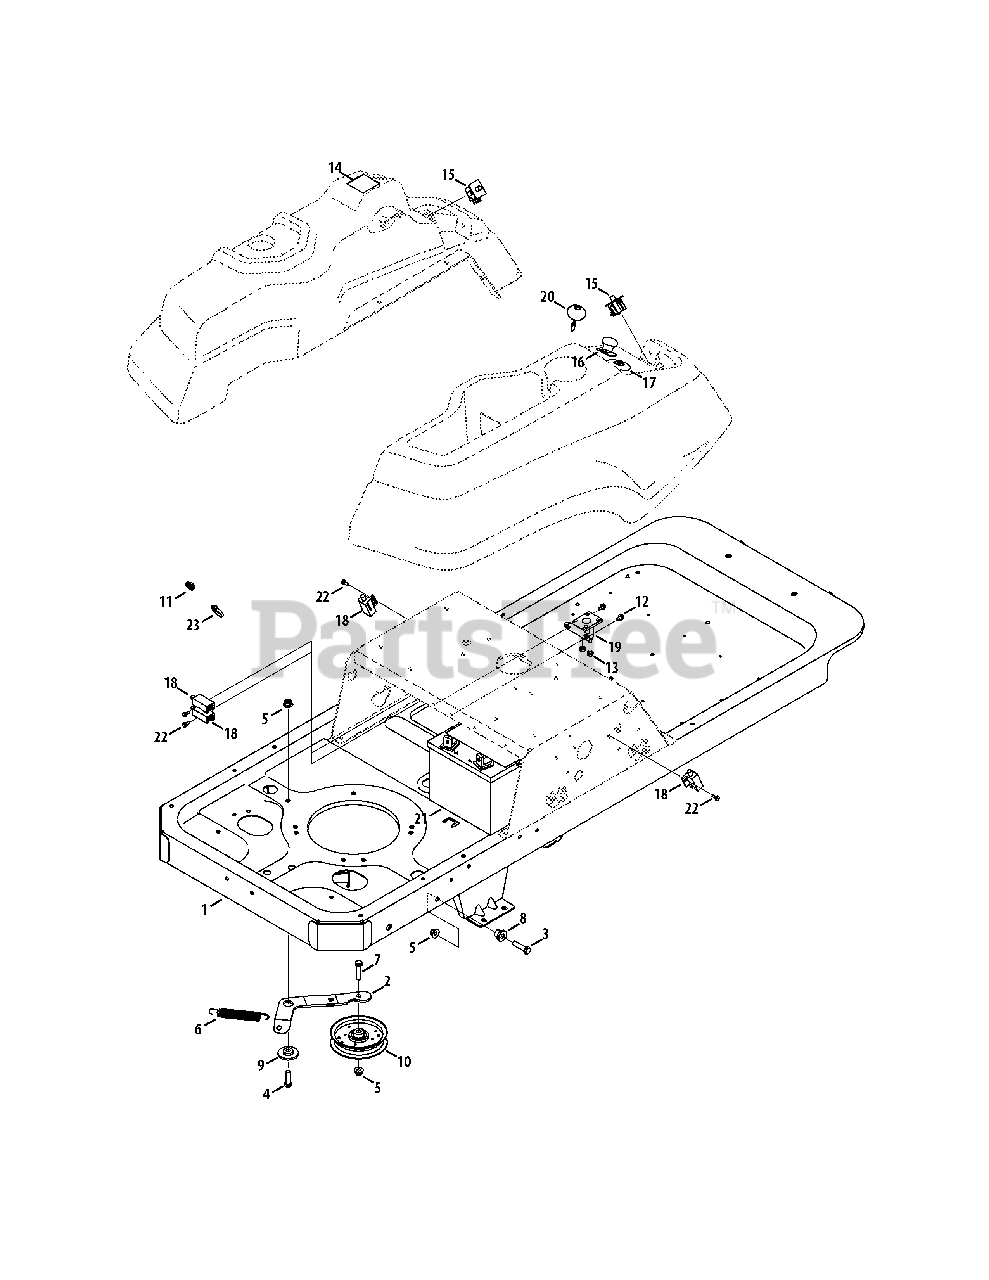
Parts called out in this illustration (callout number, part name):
1	Frame Assembly
3	Hex Screw, 3/8-16 x 1.5
4	Hex Screw, 3/8-16 x 1.25
5	Flange Nut, 3/8-16
6	Extension Spring, .75 x 5.06
7	Hex Screw, 3/8-16 x 1.5
8	Shoulder Spacer, .39 x 1.0 x .7
9	Shoulder Spacer, .884 x .19
10	Idler Pulley, 4.25 Dia.
11	Wire Harness
12	Hex Screw, 1/4-20 x .375
13	Hex Nut, 1/4-20
15	Neutral Switch
16	PTO Switch
17	Ignition Switch
18	Interlock Switch
19	Solenoid
20	Key
22	Shoulder Screw, #10-32 x .500
23	Cable Tie
